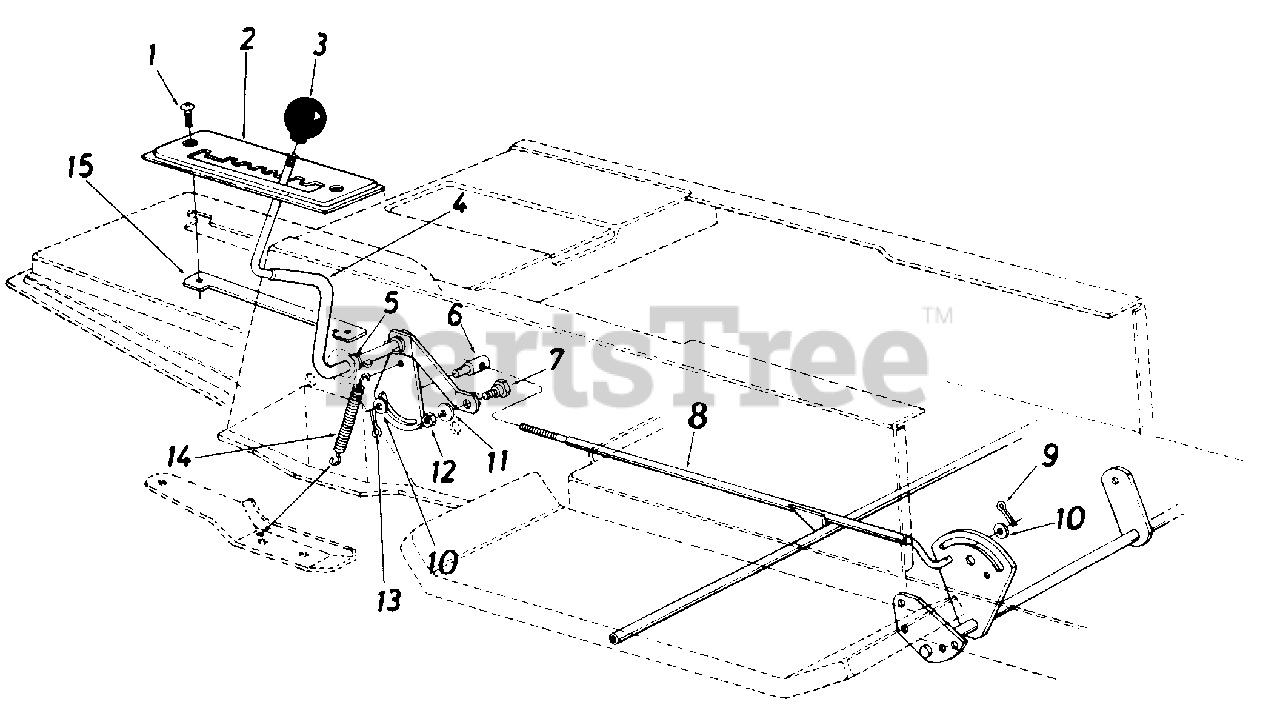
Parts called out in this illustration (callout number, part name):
1	Truss Mach. Scr. 1/4-20 x .75" Lg.
2	Speed Selector Plate 4-Speed
4	Speed Selector Cam Ass'y.
5	Flat Washer .53" I.D. x .93" O.D.
6	Ferrule 3/8-24 x .37" Dia.
7	Shoulder Bolt .435" Dia. x .160
8	Speed Control Rod Ass'y.
9	Cotter Pin 3/32" Dia. x .75"
10	Fl-Wash. .469" I.D. x .88" O.D.
11	L-Wash. 5/16" I.D.
12	Hex Nut 5/16-18 Thd.*
13	Cotter Pin 8/32" Dia. x .75" Lg.*
14	Spring .38" O.D. x 3.18" Lg.
15	Clamping Plate
